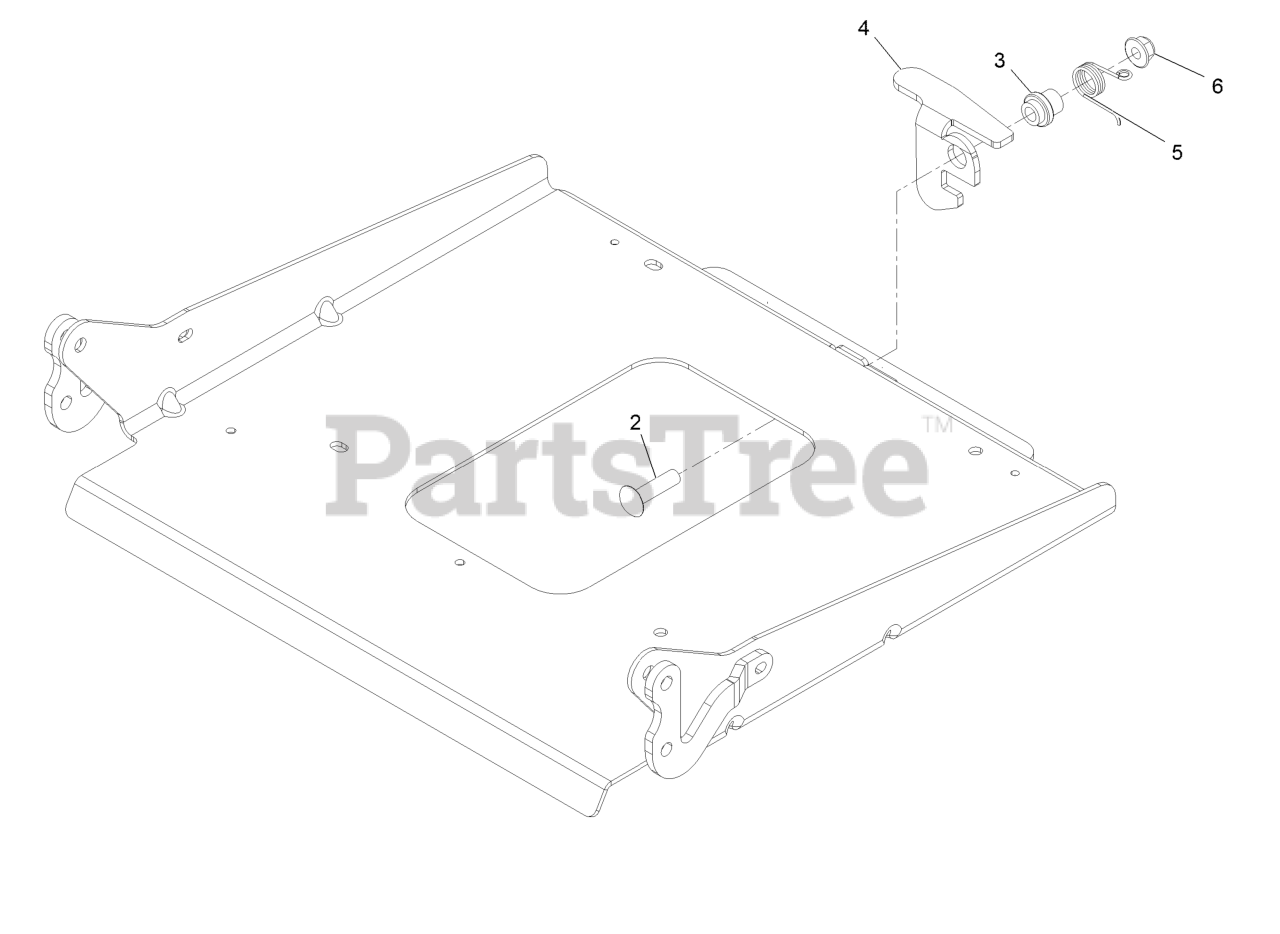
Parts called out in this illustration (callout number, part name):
2	Screw-CARR
3	Bushing-Latch, Seat
4	Latch-Catch, Single
5	Spring-Torsion, Latch
6	Nut-Flange, NI
